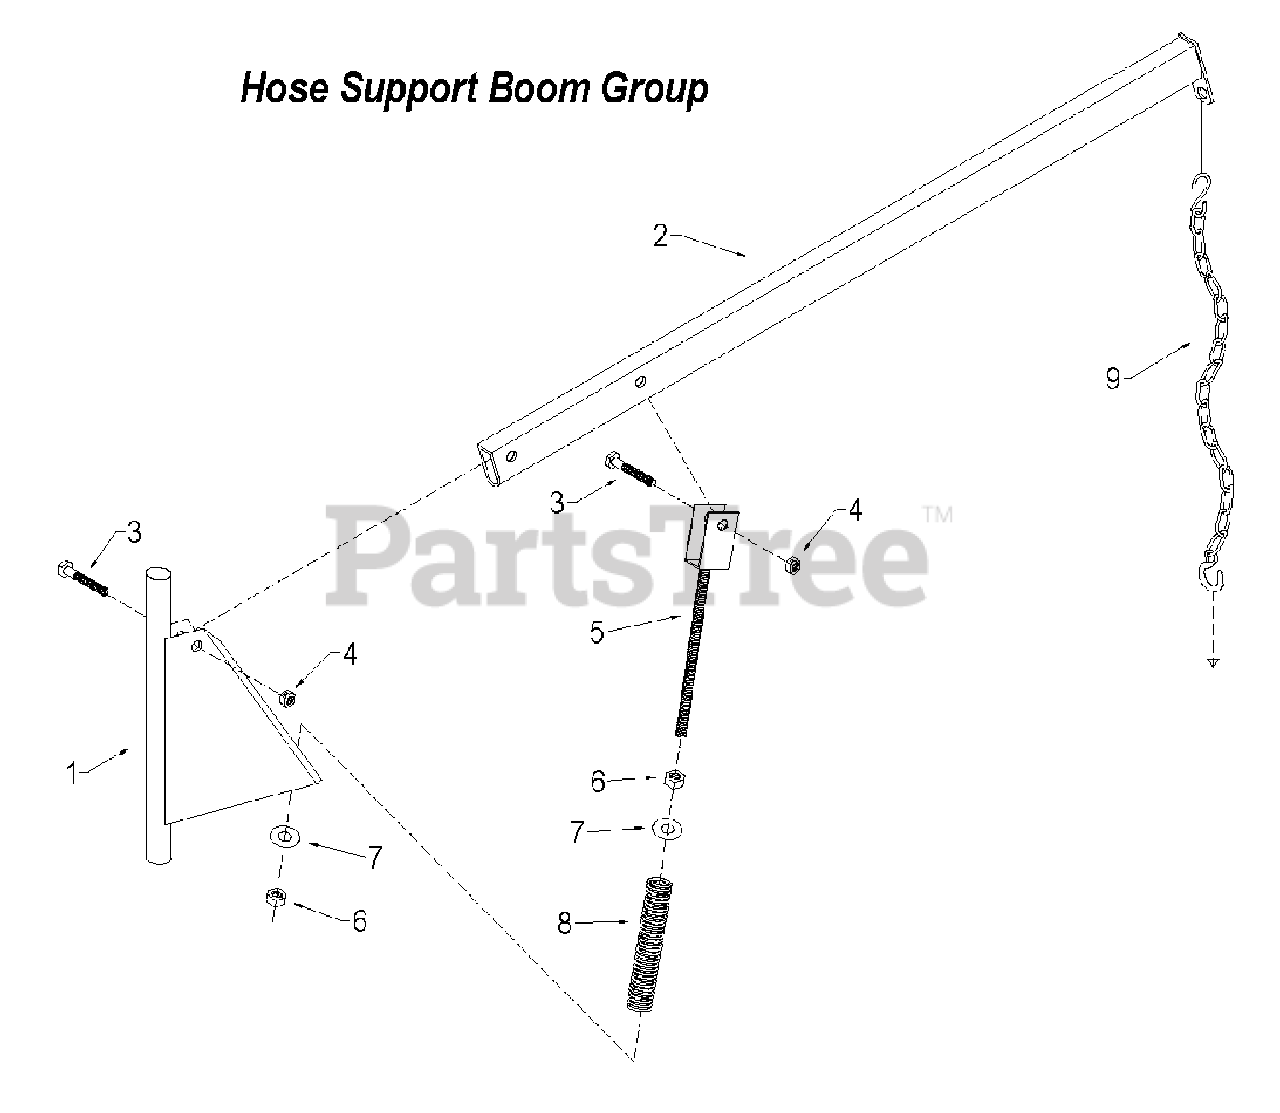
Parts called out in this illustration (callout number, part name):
1	Boom vertical member new bearing style
2	Boom horizontal member
3	Bolt, hex – 1/2-13 x 3"
4	Nut, reverse lock – 1/2-13
5	Guide, threaded spring
6	Nut, hex – 3/4-10
7	Washer, flat – 3/4"
8	Spring, boom
9	Chain, boom – 48 w/2 S-hooks
